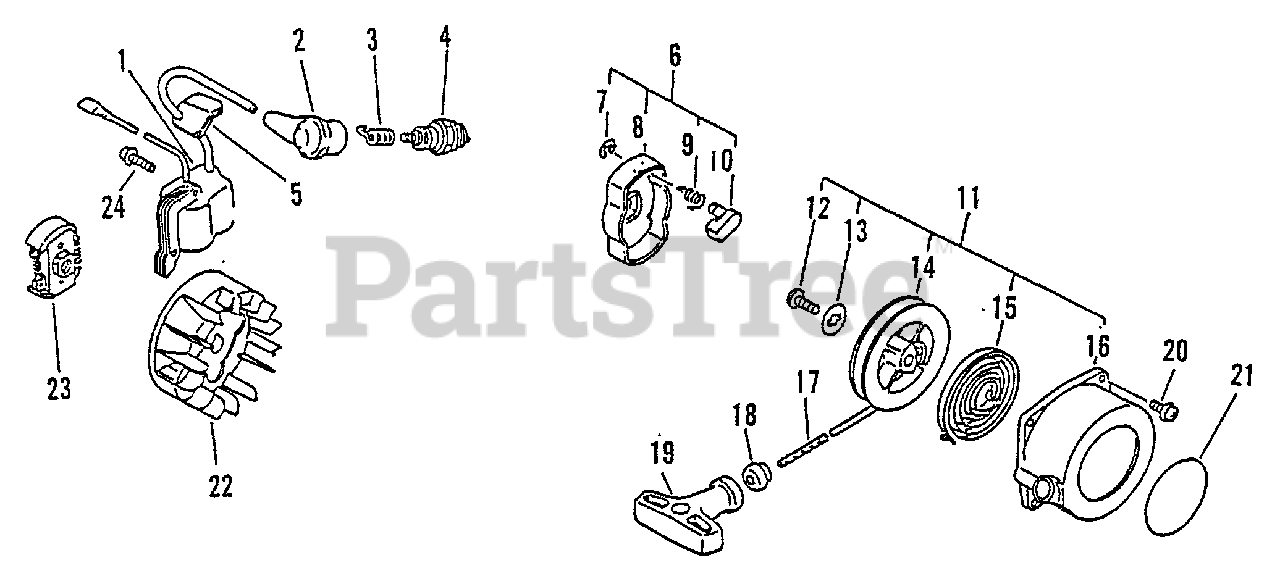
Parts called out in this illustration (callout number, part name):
1	COIL, IGNITION
2	CAP, SPARK PLUG
3	TERMINAL, SPARK PLUG
4	SPARK PLUG - BPM7A
6	STARTER PAWL ASSY
7	E-RING 4
8	CATCHER, PAWL
9	SPRING, RETURN
10	PAWL, STARTER
11	STARTER ASSY
13	WASHER
14	REEL, ROPE
15	SPRING, RECOIL
16	CASE, RECOIL STARTER
17	ROPE, STARTER
18	GUIDE, ROPE
19	GRIP, STARTER
20	SCREW 4×16
21	LABEL, ECHO
22	FLYWHEEL
23	CLUTCH ASSY
24	SCREW 4×22
